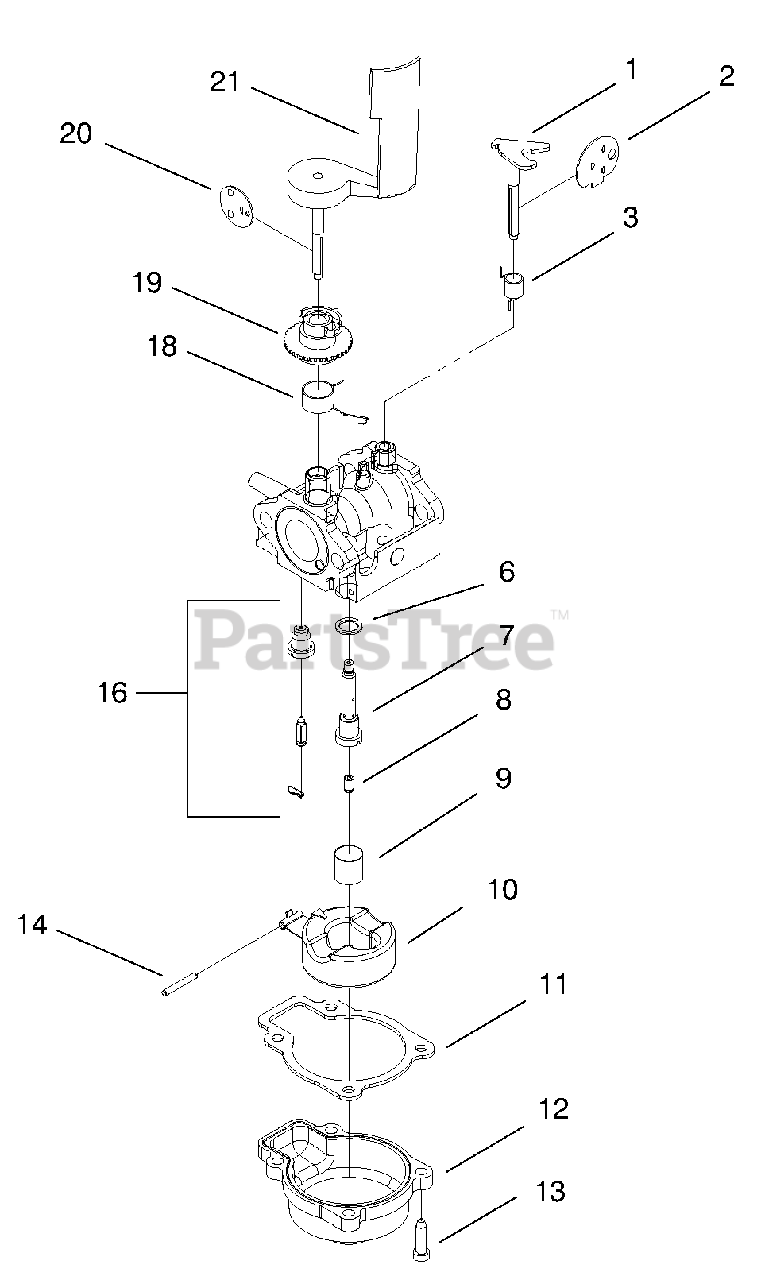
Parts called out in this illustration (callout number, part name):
1	SHAFT-CHOKE
2	DISC-CHOKE
3	SPRING-CHOKE
8	JET-MAIN
9	FILTER-FUEL
10	FLOAT AND ARM ASM
12	CHAMBER-FLOAT
13	SCREW-HH
14	PIN-STRAIGHT
16	VALVE/SEAT-FLOAT
18	SPRING-THROTTLE
19	COLLAR-ADJUST, AIRVANE
20	DISC-THROTTLE
21	Air Vane&shaft
